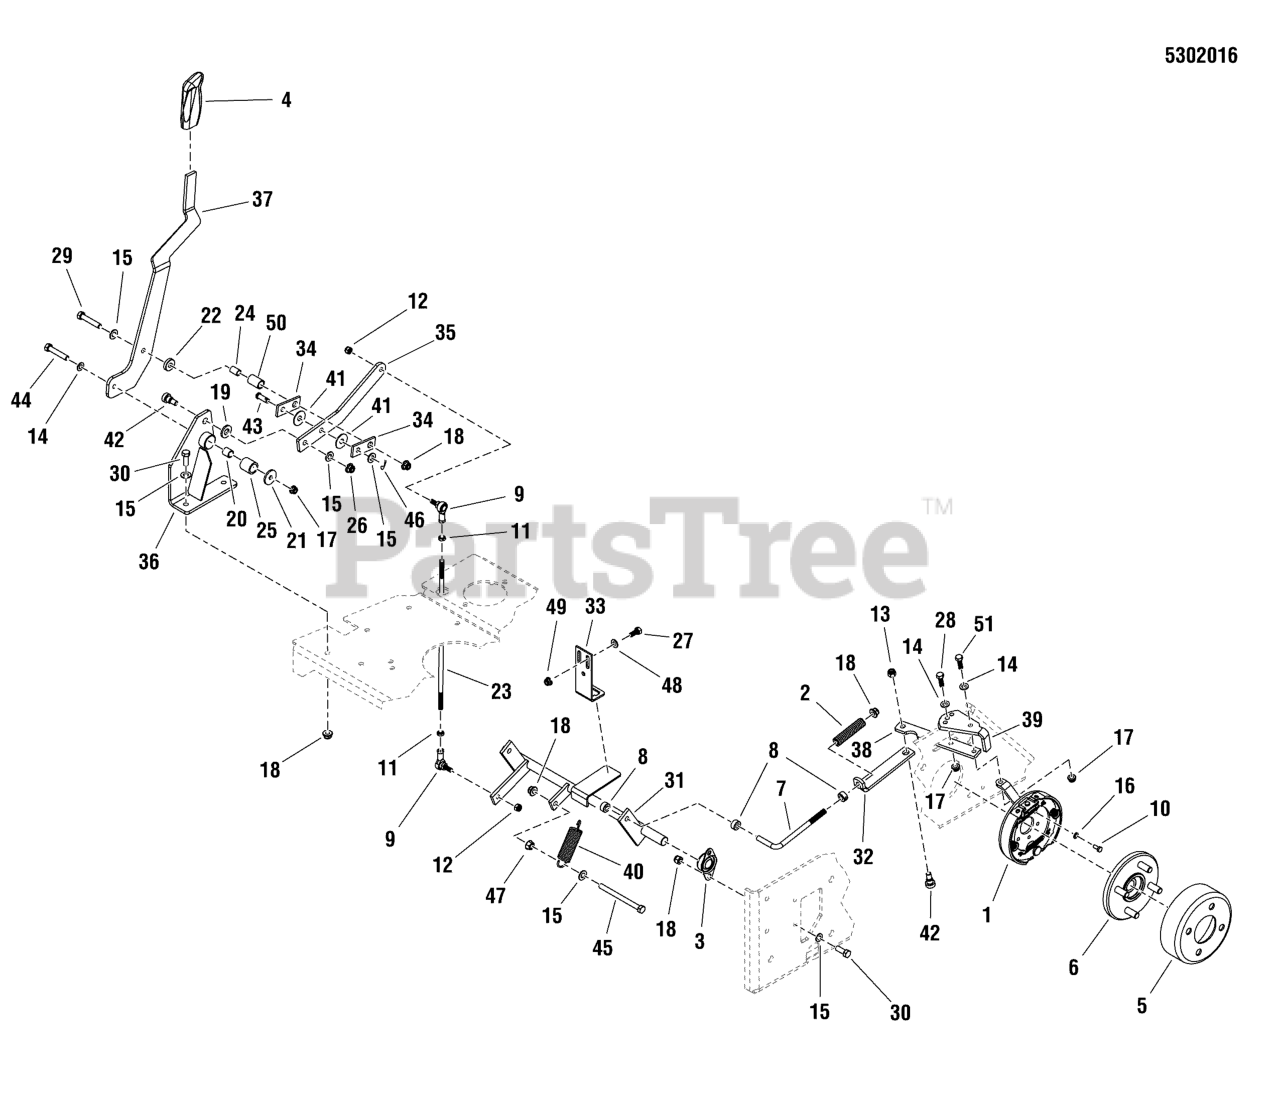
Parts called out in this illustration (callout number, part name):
1	CAM BRAKE SHOE ASSM, KNOTT
2	SPRING-COMP, .496ID X 3.00LG X .112WR
3	BEARING, BRONZE FLANGE, 3/4"
4	GRIP, BLACK FLEXIBLE
5	BRAKE DRUM
6	HUB-W/STUD, 1TPR 800645
7	ROD, BRAKE LINKAGE
8	COLLAR, 3/8 SET
9	BALL JOINT 5/16-24 LH FEMALE W/STUD, BR
10	CAPSCREW-HEX HEAD M6-1.0X 14MM
11	NUT, 5/16-24 JAM
12	NUT, 5/16-24 HEX NYLON LOCK
13	NUT, 3/8-16 HEX NYLON LOCK
14	WASHER, 5/16" SAE
15	WASHER, 3/8 SAE
16	WASHER, 1/4 LOCK
17	NUT, 5/16-18 HEX NYLOCK FLANGE
18	NUT, 3/8-16 HEX NYLOCK FLANGE
19	WASHER, 1/2 GD9 YZ
20	SPACER, .32 X .75 X 1.06
21	WASHER, .34 X 1.25 X 10 GA
22	SPACER, .39 X 1.00 X .25
23	ROD, CHUTE PIVOT
24	SPACER, .38 X .50 X .75
25	BUSHING, BRASS, 3/4 X 1 X 1
26	NUT, 3/8-16 SIDE LOCK
27	BOLT,1/4-18 X 3/4 GD5
28	BOLT, 5/16-18 X 1 GD5 YZ
29	BOLT, 3/8-16 X 2, GD5, CZ
30	BOLT, 3/8-16 X 1" GD5 CZ
31	WELD, BRAKE SHAFT, 36 - RED
32	BAR, BRAKE BRACKET -RED
33	PLATE, SWITCH BRACKET - RED
34	PLATE, BRAKE HANDLE TAB - RED
35	PLATE, BRAKE HANDLE BRACKET - RED
36	WELD, BRAKE HANDLE MOUNT - RED
37	PLATE, HANDLE, PARKING BRAKE - RED
38	LINKAGE, BREAKE LOWER, 36 - RED
39	PLATE, LINKAGE ADJUSTABLE, LH - RED
40	SPRING-EXTN 1.040ODX 04.000LG .105WIRE D
41	WASHER-3/8 FENDER
42	BOLT, 3/8-16 X 3/8, 1/2 SHOULDER
43	PIN, CLEVIS, 3/8 X 1
44	BOLT, 5/16-18 X 2, GD5
45	BOLT, 3/8-16 X 4-1/2" GD5 CZ
46	COTTER PIN, 1/8 X 3/4
47	NUT, 3/8-16 HEX SERRATED FLANGE
48	WASHER, 1/4 SAE
49	NUT, 1/4-20 HEX NYLOCK FLANGE
50	SPACER, .564 X .904 X .310, YZ
51	BOLT, 5/16-18 X 1-1/4 GD5 YZ
